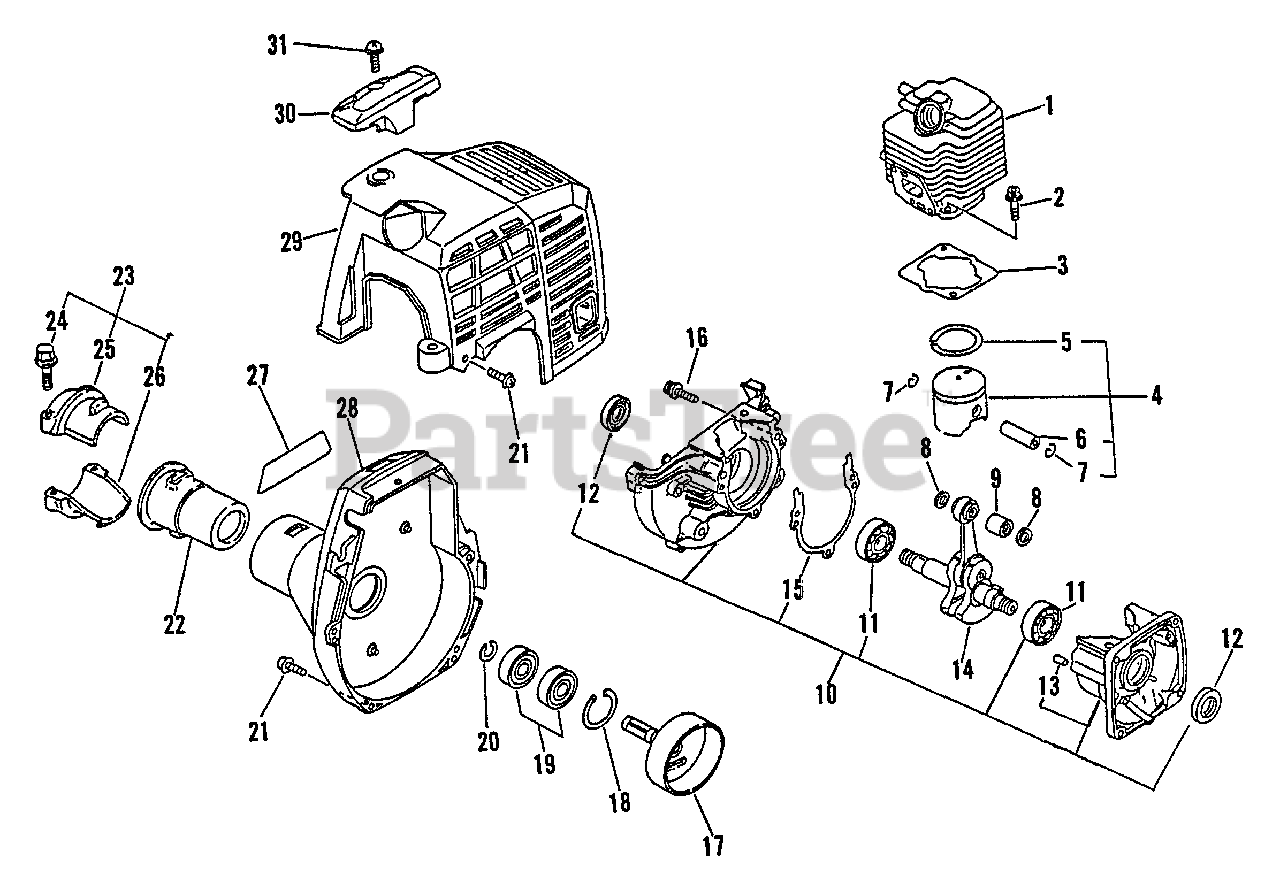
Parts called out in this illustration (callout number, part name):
1	CYLINDER
2	BOLT 5×22
3	GASKET, CYLINDER
4	PISTON KIT
5	RING, PISTON
6	PIN, PISTON 8
7	RING, SNAP
8	WASHER, THRUST
9	BEARING, NEEDLE
10	CRANKCASE KIT
11	BEARING, BALL 6201
12	SEAL, OIL 12
13	PIN, LOCATING 4×8
14	CRANKSHAFT ASSY
15	GASKET, CRANKCASE
16	SCREW 5×28
17	DRUM, CLUTCH
18	RING, SNAP 28
19	BEARING, BALL 6001
20	RING, RETAINING - 12
21	SCREW 4×16
23	HOLDER KIT
24	BOLT - 5×25
25	HOLDER, MAIN PIPE - UPPER
27	LABEL - MODEL SRM-1501(92)
28	FAN CASE ASSY
29	COVER, ENGINE
30	GUARD, TOP
31	SCREW 5×16
